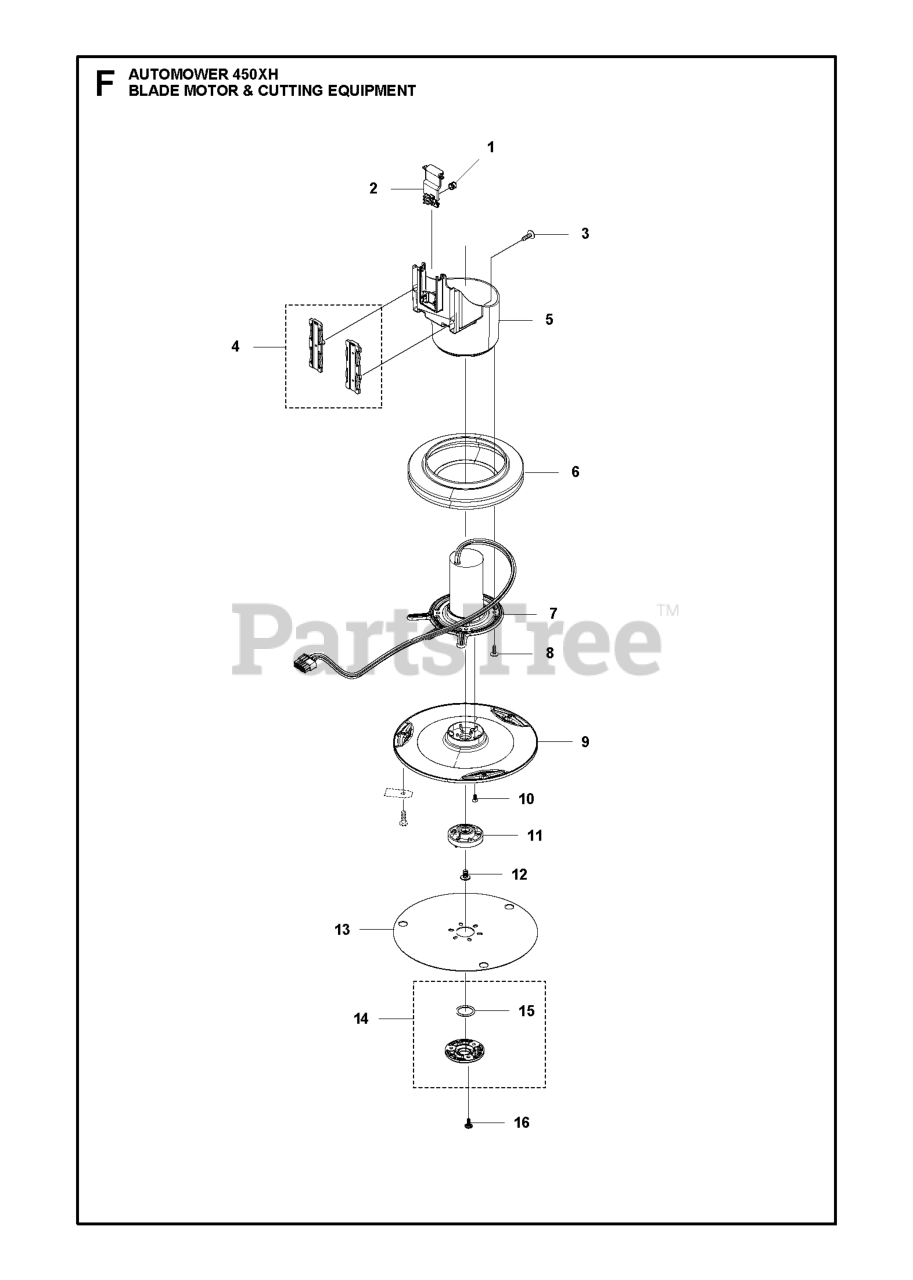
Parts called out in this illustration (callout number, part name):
1	SPRING LINK
2	LINK MOTOR HOUSING
3	SCREW 14MM
4	BEARING KIT
5	HOUSING CUTTING MOTOR
6	BELLOWS CUTTING SYSTEM
7	MOTOR ASSY JE
8	SCREW 14MM
9	CUTTING DISC
10	SCREW TORX M4X8 8.8 NYLON PATC
11	BEARING HOUSING ASSY
13	SKID PLATE
14	COVER KIT BEARING
15	O-RING 20X2,5 MM
16	SCREW 14MM
